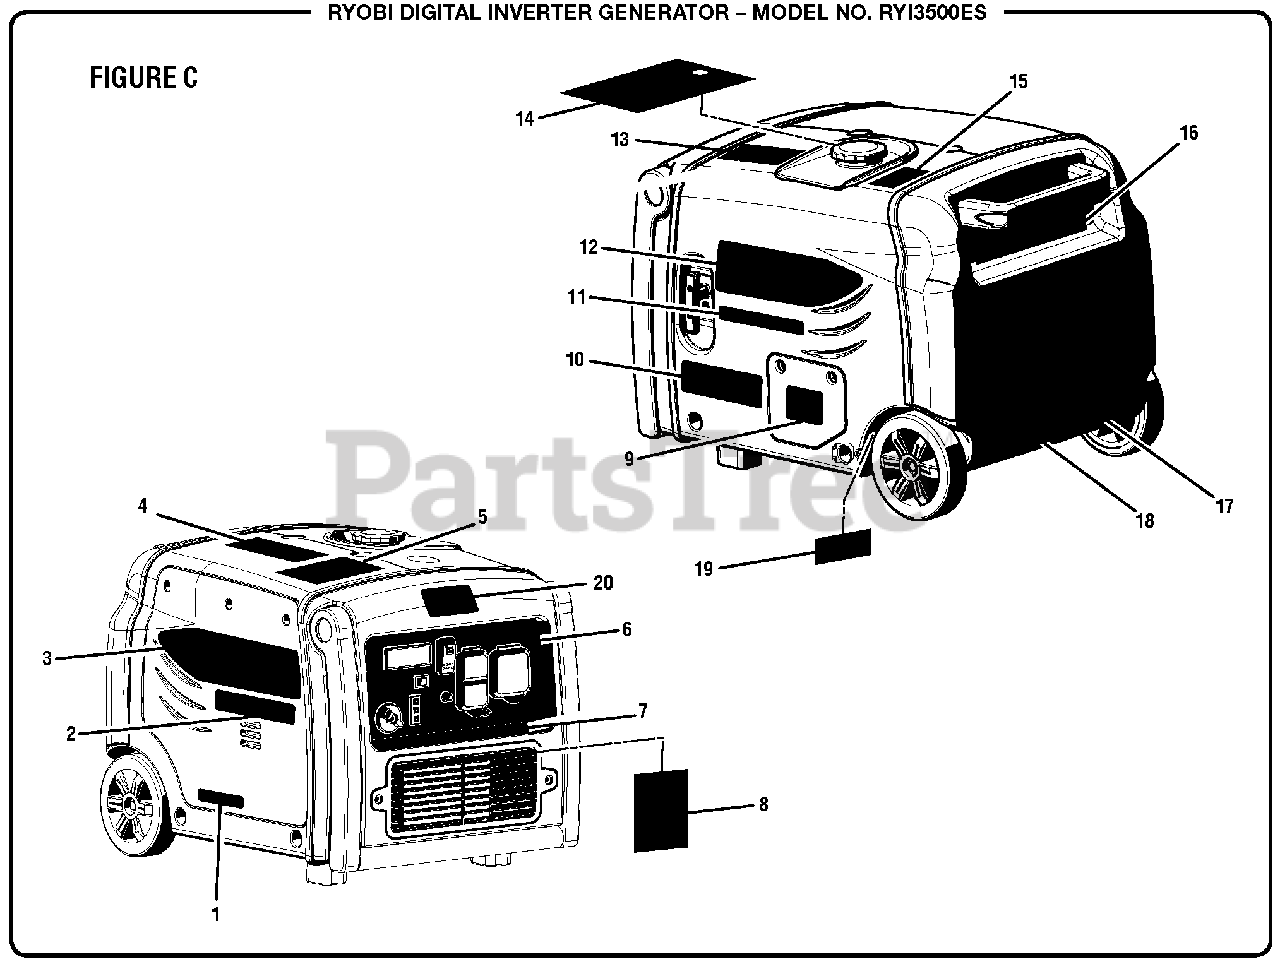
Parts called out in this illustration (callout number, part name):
1	Inquiries Label
2	Electric Start Label
3	Left Side Performance Label
4	Danger Label
5	CPSC Danger Label
6	Outlet Panel Label
7	Ground Warning Label
8	Battery Connection Hangtag (Temporary)
9	Lubricant Label
10	Large Logo Label
11	Start Label
12	Right Side Performance Label
13	Fuel Stabalizer Label
14	Notice Hangtag Label
15	E85 Label
16	Fire Danger Label
17	Hot Surface Label
18	Combustion Label
19	Internally Placed Maintance Label
20	Small Logo Label
